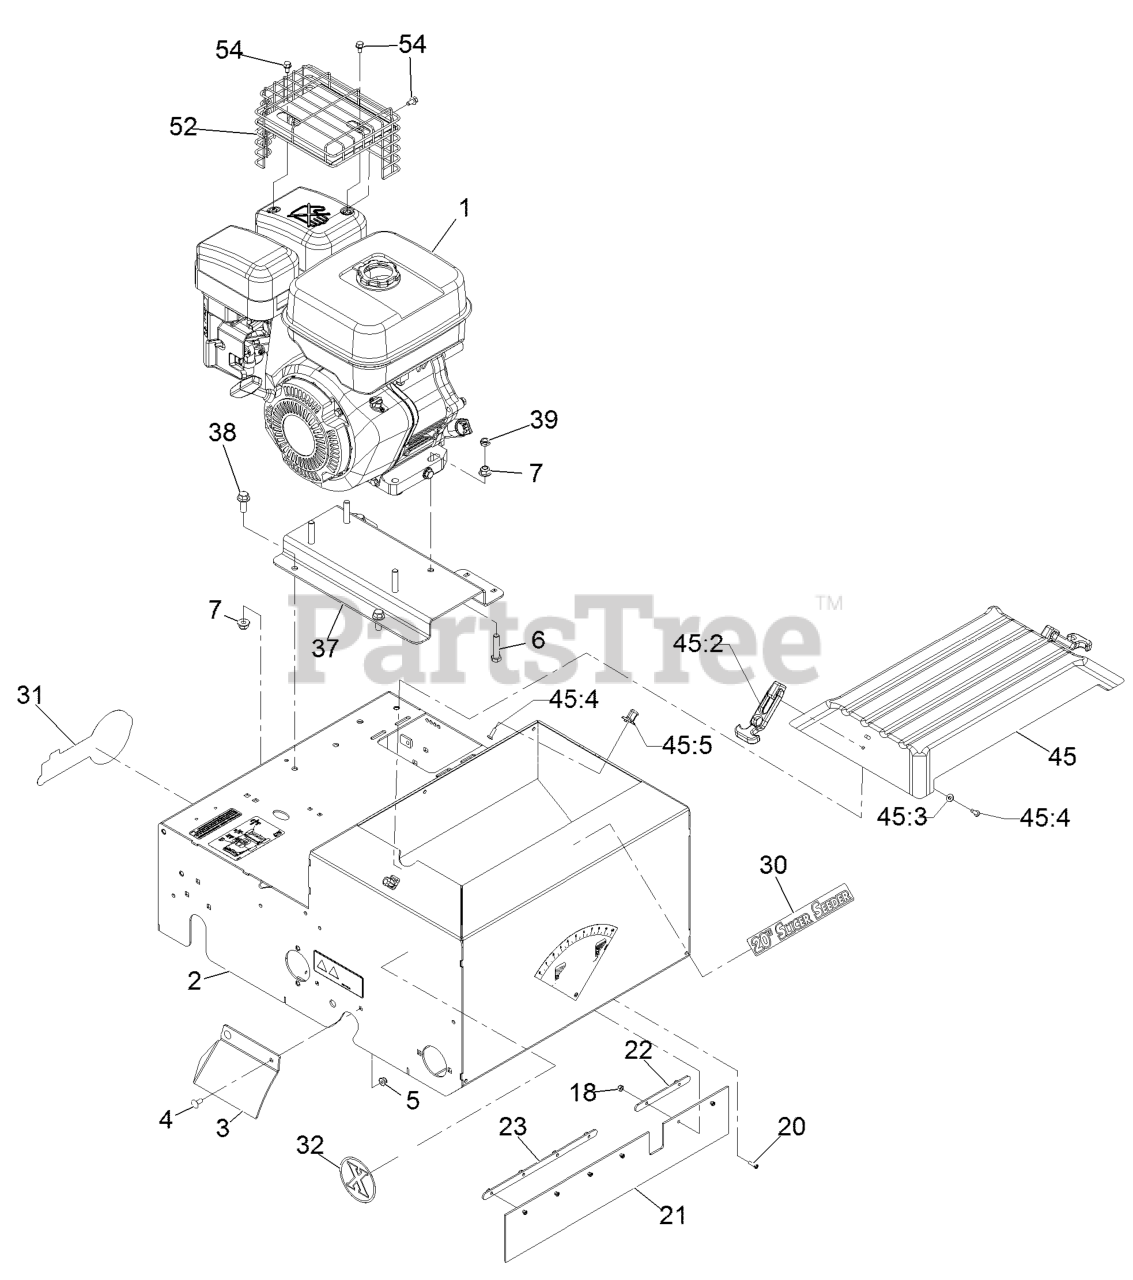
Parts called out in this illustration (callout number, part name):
2	FRAME ASM
4	SCREW-CARR
6	SCREW-HH
7	NUT-HF, NI
18	NUT-LOCK
20	SCREW-SHH
21	GUARD-DUST
22	PLATE-RETAINER
23	PLATE-RETAINER
30	DECAL-SLICER SEEDER 20
31	DECAL,EXMARK LOGO
32	DECAL-EXMARK X-LOGO 3.26
37	PLATE-ENGINE
38	SCREW-HHF 3/8-16 X 1
45	SEEDER COVER KIT
45:2	LATCH-RUBBER
45:3	WASHER-FLAT
45:4	SCREW-PPH
45:5	LATCH-KEEPER
52	GUARD, MUFFLER
54	SCREW-HWH
